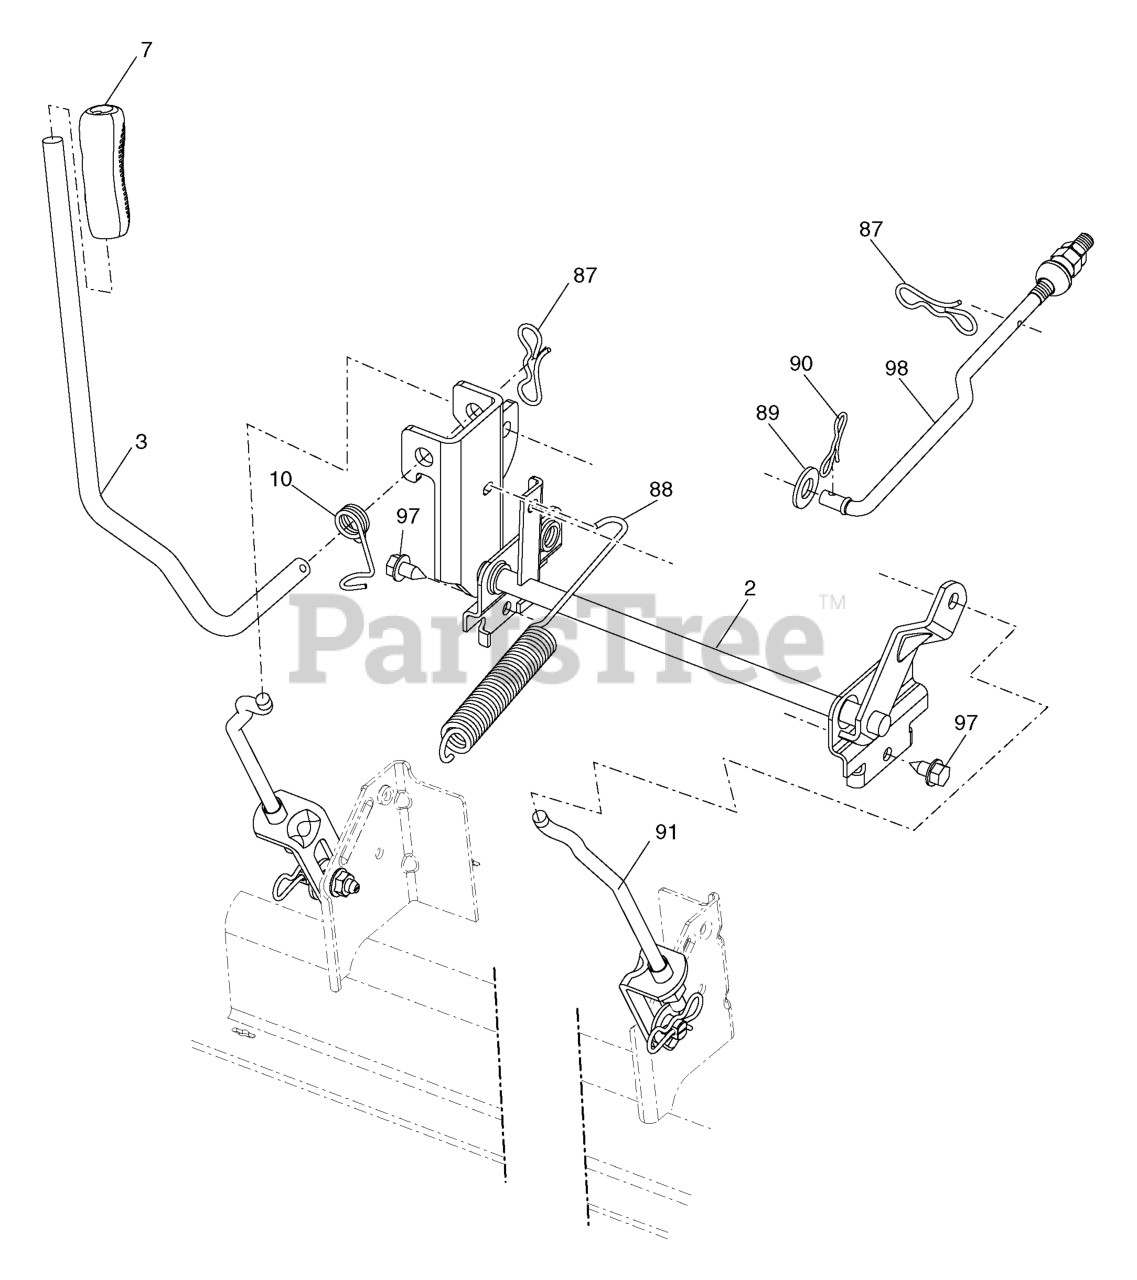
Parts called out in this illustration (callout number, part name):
2	SHAFT.ASM.LIFT.CROSS.H
3	LEVER.LIFT.HANDLE.GT
7	GRIP.LEVER.5625.ID
10	SPRING.TORSION.LIFT.HANDLE
87	PIN.COTTER.7/16.BOW TI.
88	SPRING.LIFT.ASSIST.GT2
89	WASHER.CLEAR.ZINC
90	PIN.COTTER.5/16.BOW TI
91	LINK.ASM.LIFT.REAR
97	SCREW 3/8-16X3/4
98	LINK.ASM.SUSP.FRONT.MW
